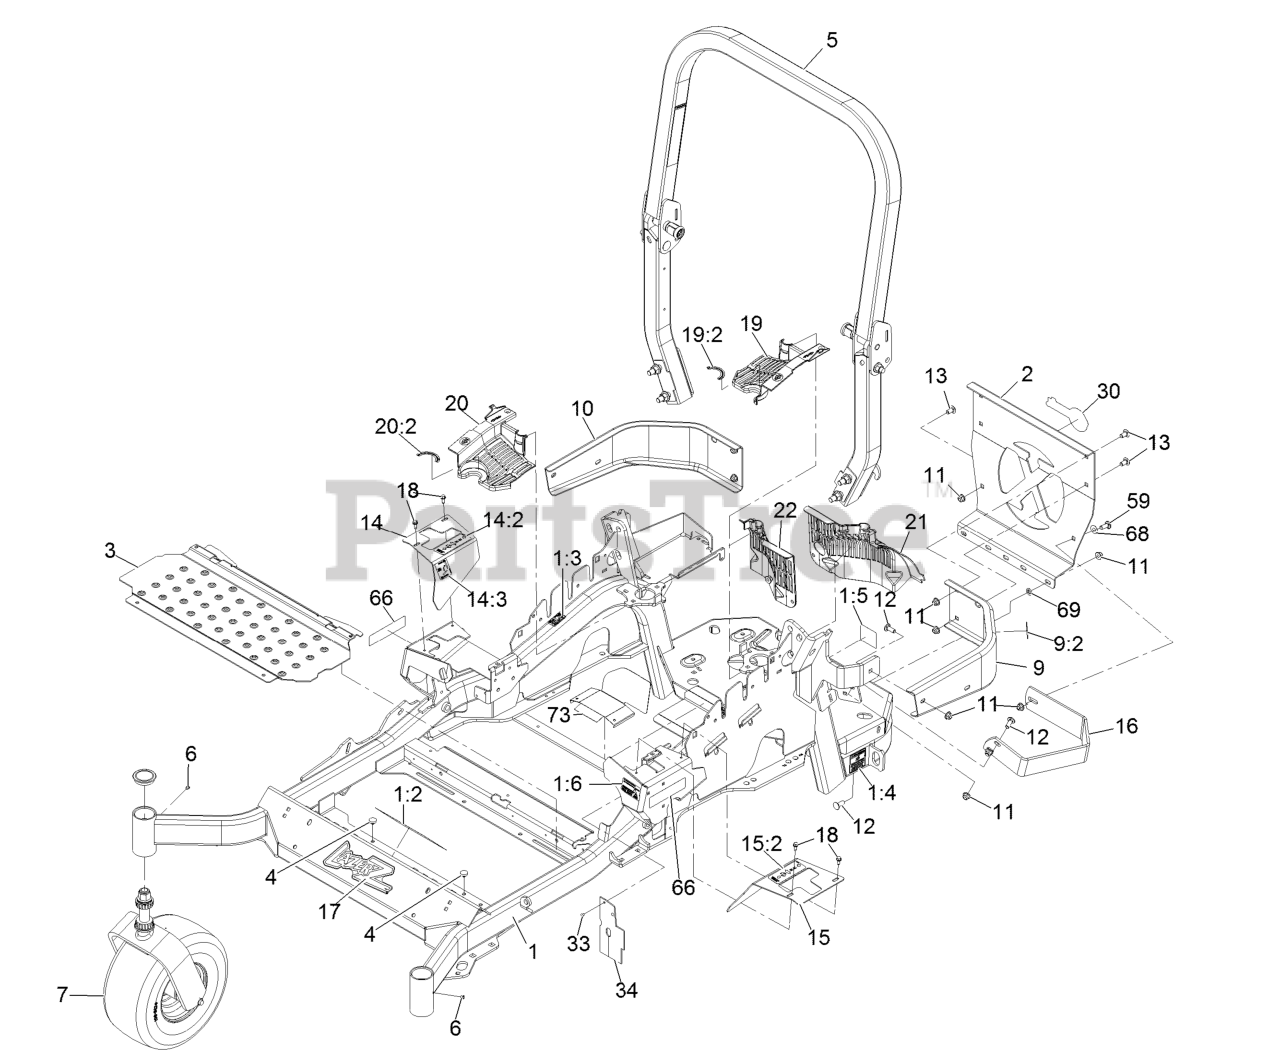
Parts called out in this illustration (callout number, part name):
1	MAINFRAME ASM
1:3	DECAL-SLOPE
1:4	DECAL-BELT DRIVE
1:5	DECAL-SPARK ARRESTER
1:6	DECAL-FUEL FILL
2	PLATE,REAR GUARD
5	ASM,ROPS SERVICE EXMARK
7	Caster Wheel Asm
9	LH BUMPER ASM
9:2	DECAL-CAUTION
10	BUMPER-RH
11	NUT-HF, NI
12	DECAL-CAUTION
12	SCREW-CARR
13	SCREW-CARR
14	RH MOTION CONTROL COVER ASM
14:2	DECAL-MOTION CONTROL
14:3	DECAL-PARK BRAKE
15	LH MOTION CONTROL COVER ASM
15:2	DECAL-MOTION CONTROL
17	DECAL,LAZER MODEL
18	SCREW-HWH
19	LH HYDRO GUARD ASM
19:2	DECAL-HYDRO OIL
20	RH HYDRO GUARD ASM
20:2	DECAL-HYDRO OIL
21	GUARD-HYDRO REAR, LH TRIM
22	GUARD-HYDRO, REAR (RH)
33	RIVET-POP
34	DEFLECTOR-AIR FLOW
59	SCREW-HH
66	DECAL-X-SERIES
68	WASHER-FLAT
69	NUT-PUSH
73	GUARD-EXHAUST
